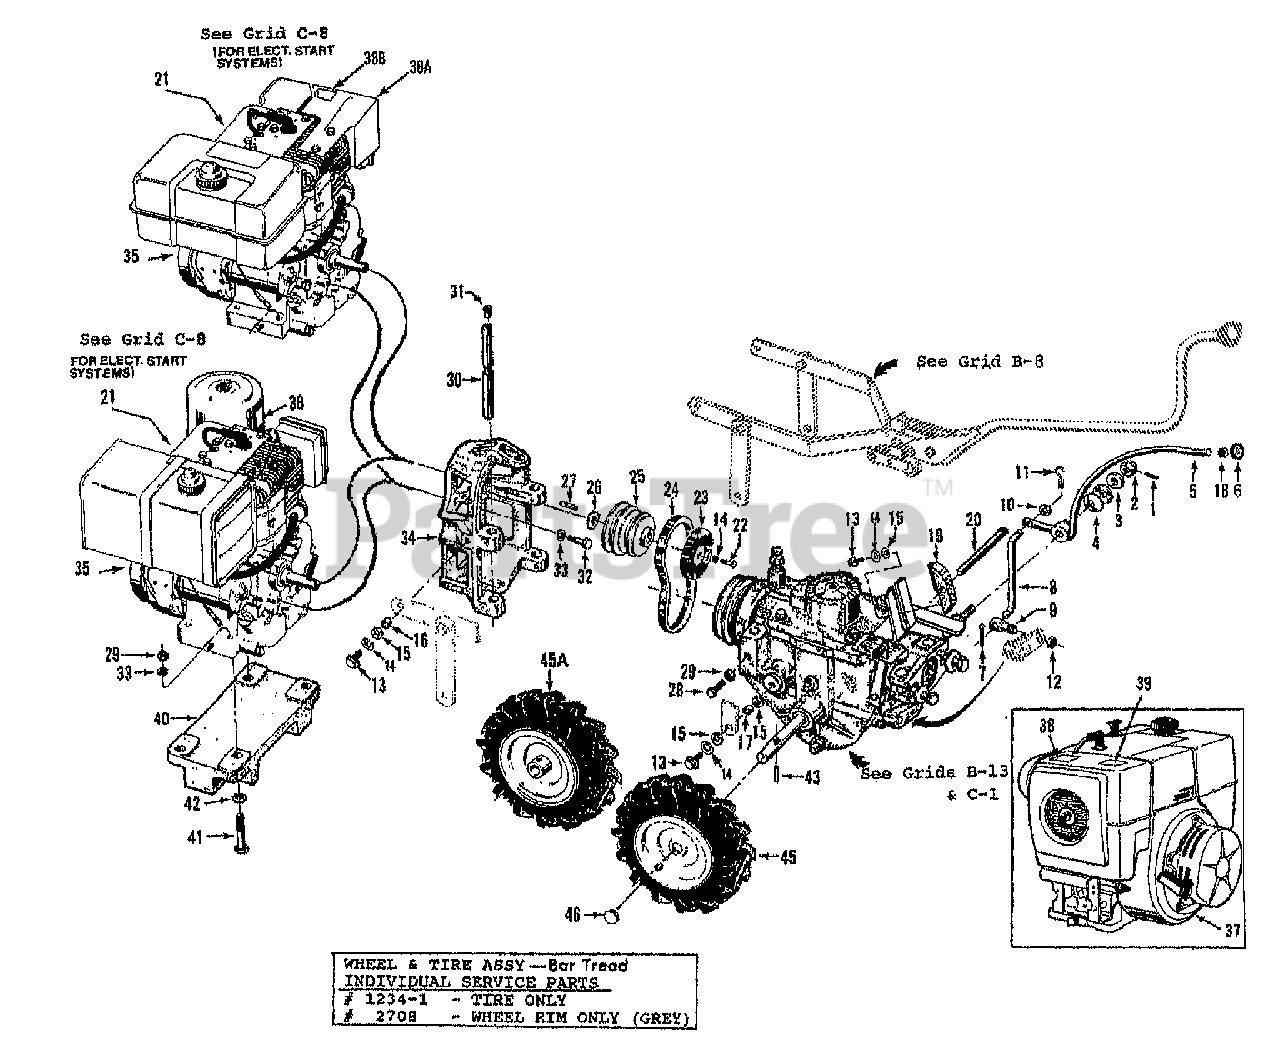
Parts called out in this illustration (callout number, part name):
1	PIN-SPRING .125 X 1
2	NUT-HEX 1/2-20 (SLOTTED)
3	WASHER-# SHOULDER ZP
4	WASHER-# 1.97X1X.118
5	LVR-W/KNOB (WHEEL SPEED) (INCL. 6 & 18)
6	KNOB-WHEEL SPEED HORSE (INCL. 18 & PLASTIC DECAL INLAY)
7	PIN-COTTER .094X1.0
8	ROD-CONNECTING
9	SWIVEL
10	WASHER-FLAT 5/16 SAE
11	PIN-CLIP .08
12	NUT-H/LK 5/16-18
13	SCR-HH 3/8-16X1.0 G5 ZP
14	WASHER-LK .375 @ DEPL
15	WASHER-FLAT 3/8 SAE
16	THIS REF. NO. NOT USED
17	BUSHING-.5X.375X.3
18	RING-TOLERANCE .5325 ID
19	KIT-ADJ BLOCK 4 SP (INCL. 13, 15 & 20)
20	BAR-ADJUST, 7" W/MEASURING GAUGE
21	DECAL-STARTING STABIL, B&S
22	SCR-HH 3/8-24X1.5 G5
23	KIT-ADJ BLOCK/REV DISC (INCL. 19)
23	DISC ONLY - REVERSE, RUBBER RIMMED
24	BELT-FORWARD DRIVE
25	PULLEY-ENG MACH
26	SHIM-1.0X.7656X.062
26	SHIM-1.0X.7656X.031
27	KEY-.188 SQ X 2.33
28	BOLT-HEX HD., 5/16-18x1", GR 5
29	NUT-HEX 5/16-18 ZP
30	BAR-ENG MTG W/CAP PLUG
31	PLUG-CAP (RED)
32	BOLT-HH 5/16-24X1.125 G5 ZP
33	WASHER-LK .312 ZP
34	MOUNT-MOTOR HSE OPC PNT
35	TILLER-7HP STD HORSE
35	TILLER-7HP EL HORSE
35	TLR-HORSE 8HP STD B&S
35	TILLER-8HP EL HORSE B&S
35	OBS-HORSE 7HP STD CA
35	OBS-HORSE 7HP ELC CA
35	TILLER-8 T/B STD HORSE I/P B&S
35	TILLER-8HP T/B EL HORSE B&S I/P
37	TILLER-8HP STD PRO HORSE
37	TILLER-8HP EL PRO HORSE
37	OBS-HORSE 8HP STD CA
37	OBS-HORSE 8HP ELC CA
37	TILLER-7HP T/B STD HORSE
37	TILLER-7HP T/B ELEC HORSE
38	DECAL-HOT SURFACE
38A	GUARD-MUFFLER
38B	DECAL-HOT SURFACE
39	DECAL-STABIL STARTING
40	WEIGHT-ENG ECONO PNT
41	SCR-HH 5/16-18X2.25 G5ZP
42	SPACER-.88X.385X.09 ZP
43	PIN-SPIROL .313 X 1.5
45	ASSM-TIRE&WHEEL LH GRAY
45A	ASSM-TIRE&WHEEL RH GRAY
46	CAP-HUB BLK PLASTIC (REPLACES 9145)
